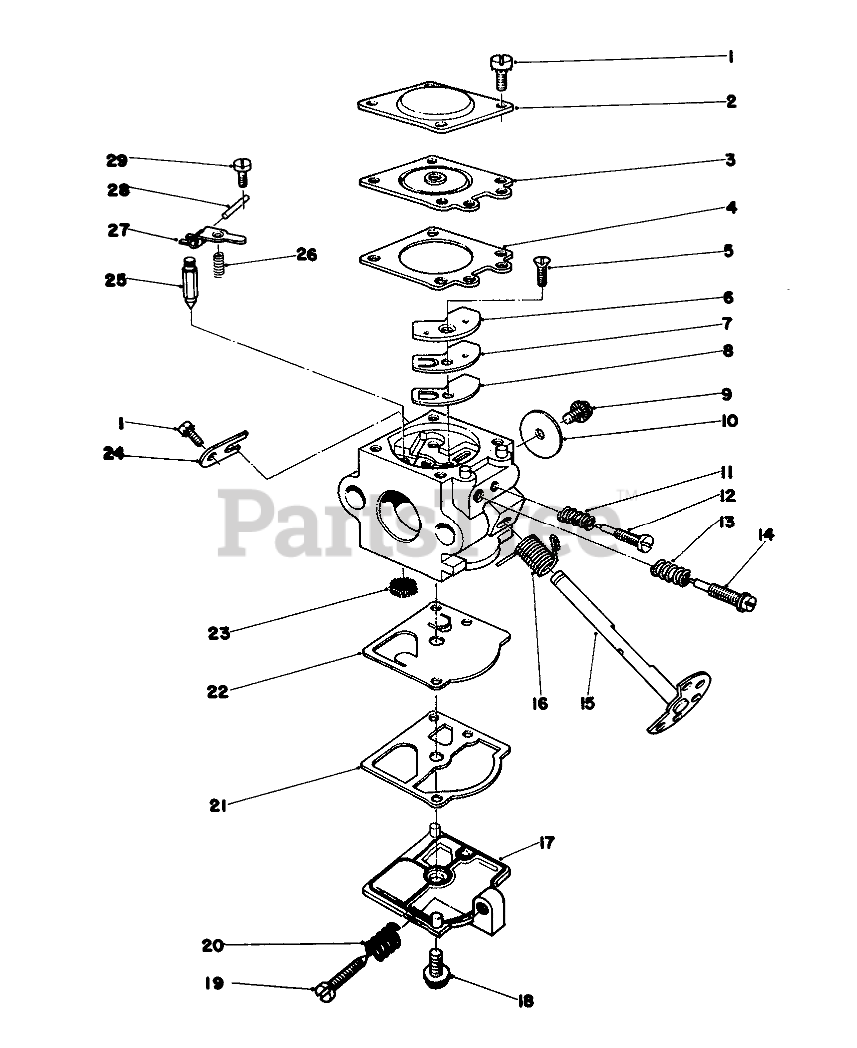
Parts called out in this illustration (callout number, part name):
1	Screw
2	Cover, Diaphragm
3	METERING DIAPHRAGM
4	Gasket, Diaphragm
5	Screw-Circuit Plate
6	Plate, Circuit
7	Diaphragm Circuit Plate
8	Gasket-Circuit Plate
9	Screw
10	Valve Throttle
11	Spring, Needle
12	Needle, Idle
13	Spring, HS Needle
14	HIGH SPEED NEEDLE
15	Shaft, Throttle
16	Spring-Throttle Lever
17	Cover, Fuel Pump
18	Screw
19	Screw, Idle Adjustment
20	Spring, Idle Screw
21	PUMP GASKET
22	Diaphragm Fuel Pump
23	Screen Inlet
24	Clip Throttle Shaft
25	INLET NEEDLE VALVE
26	Spring, Lever
27	Lever Metering
28	Metering Lever Pin
29	Screw-Metering Pin
